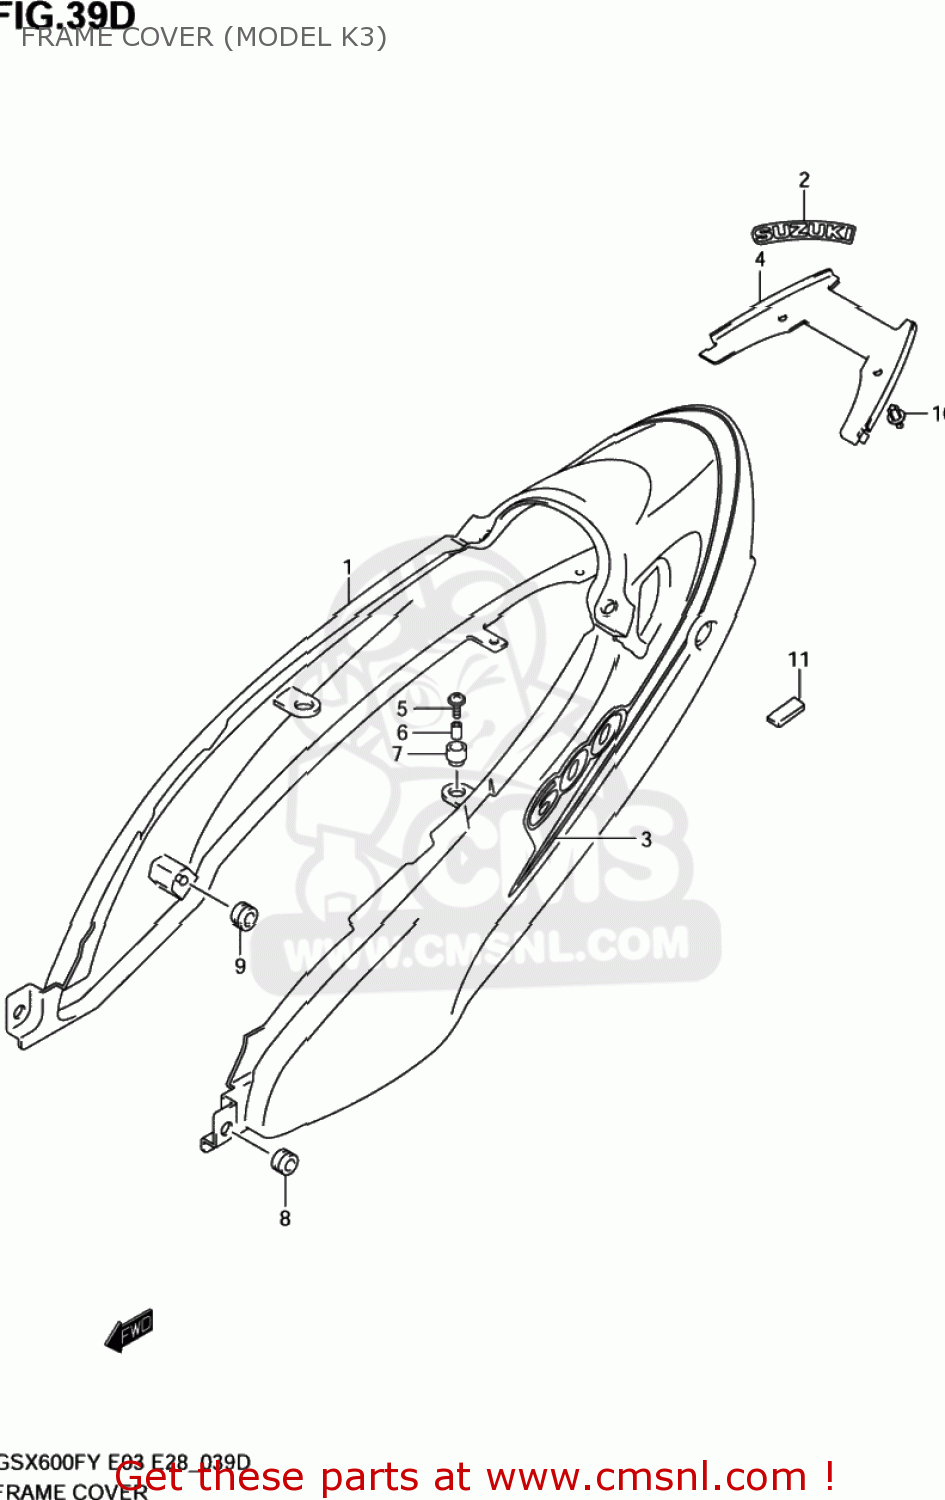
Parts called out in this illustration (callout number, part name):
1	COVER,FRAME(BLACK)
2	EMBLEM,SUZUKI
3	TAPE,FRAME COVER
4	COVER,FRAME LWR
5	SCREW(6X20)
6	SPACER(6.5X10X9.4)
7	CUSHION
8	CUSHION
9	CUSHION
10	CLIP(BLACK)
11	CUSHION
